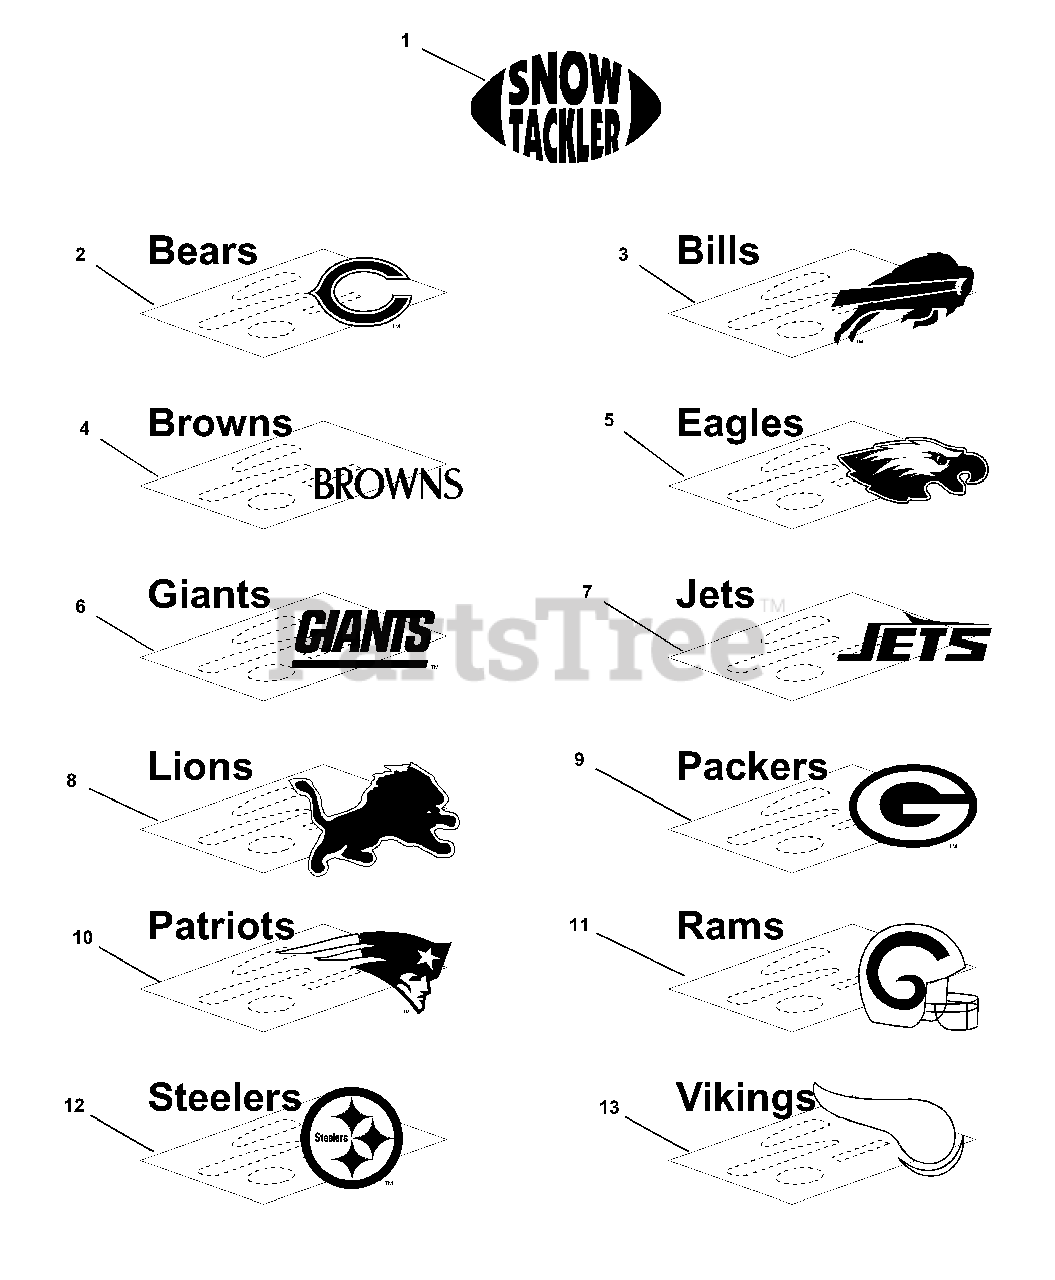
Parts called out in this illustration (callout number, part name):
1	SNOW TACKLER Decal (All Units)
2	BEARS Decal Set
2	RH Bills Logo
2	LH Bills Logo
2	Simplicity Logo
3	BILLS Decal Set
3	RH Bills Logo
3	LH Bills Logo
3	Simplicity Logo
4	BROWNS Decal Set
4	RH Browns Logo
4	Simplicity Logo
4	LH Browns Logo
4	Browns Helmet
4	RH Patriots Logo
4	LH Patriots Logo
5	EAGLES Decal Set
5	RH Eagles Logo
5	Eagle Head
5	Simplicity Logo
6	GIANTS Decal Set
6	RH Giants Logo
6	Simplicity Logo
6	Giants Helmet
7	JETS Decal Set
7	RH Jets Logo
7	Simplicity Logo
7	Jets Helmet
8	LIONS Decal Set
8	RH Lions Logo
8	Simplicity Logo
8	LH Lions Logo
9	PACKERS Decal Set
9	RH Packers Logo
9	Simplicity Logo
9	LH Packers Logo
10	PATRIOTS Decal Set
11	RAMS Decal Set
11	RH Rams Logo
11	Simplicity Logo
11	LH Rams Logo
12	STEELERS Decal Set
12	RH Steelers Logo
12	LH Steelers
12	Simplicity Logo
12	RH Steelers
13	VIKINGS Decal Set
13	RH Vikings Helmet
13	Simplicity Logo
13	LH Vikings Helmet
